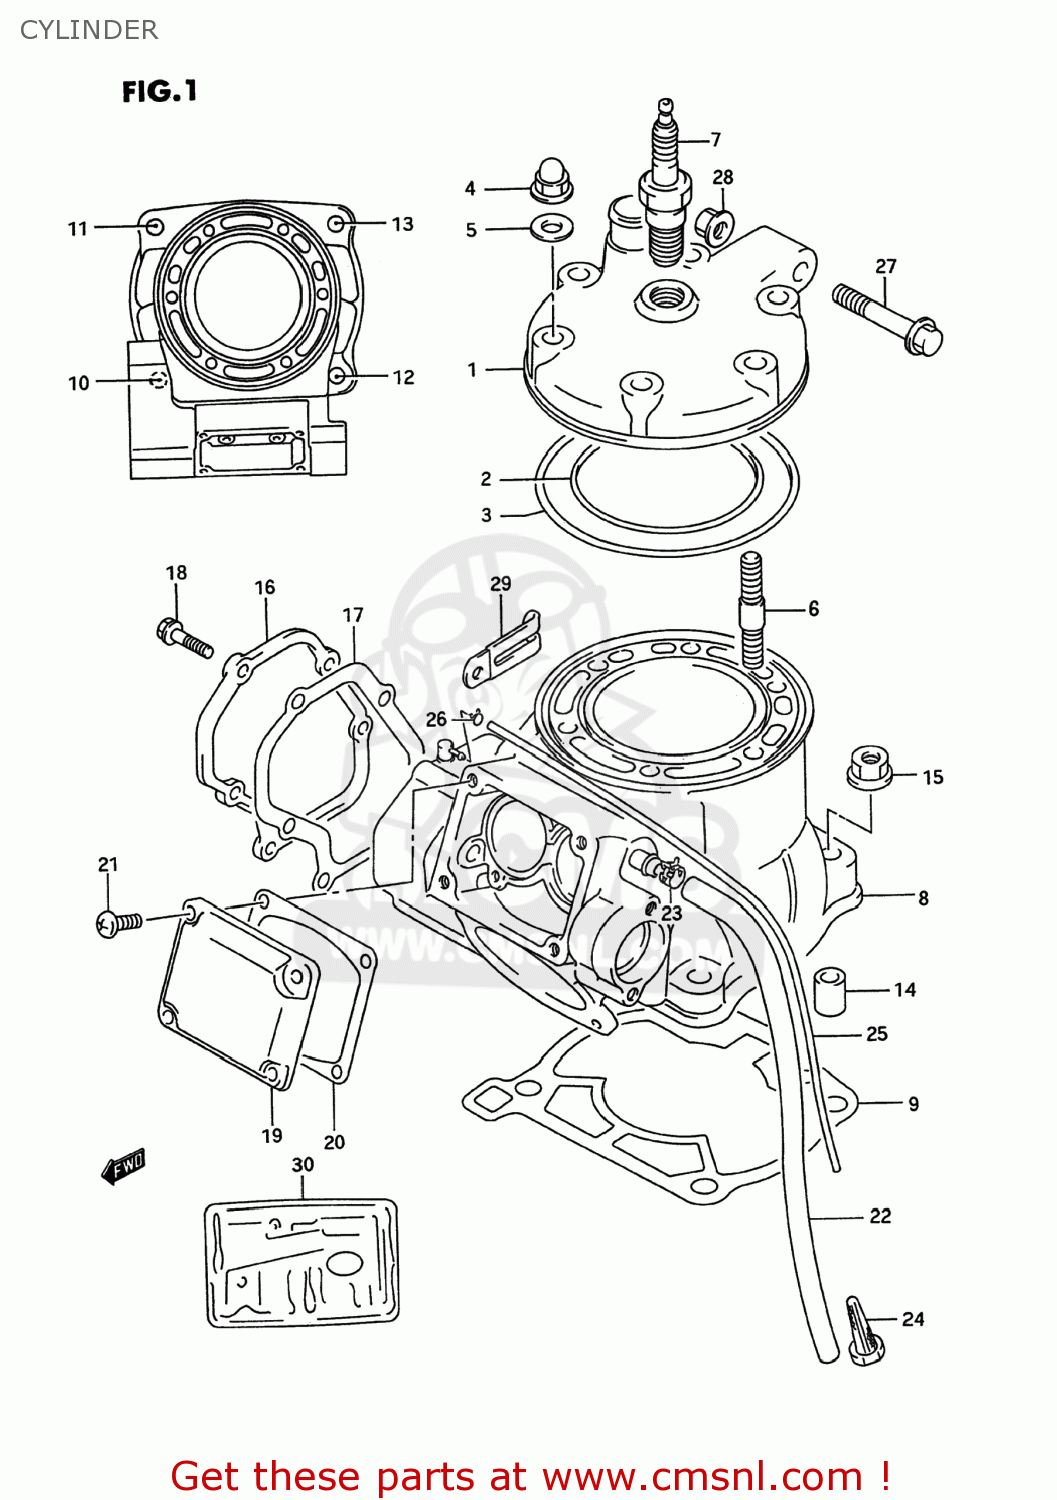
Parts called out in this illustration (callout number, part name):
1	HEAD,CYLINDER
2	O RING,CYLINDER HEAD NO.1
3	O RING,CYLINDER HEAD NO.2
4	NUT
5	GASKET(8.5X17X2.3) (NAS)
6	BOLT,STUD
7	PLUG,SPARK(R4118S-8)
8	CYLINDER SET
9	GASKET,CYLINDER (NAS)
10	STUD 10X30
11	STUD BOLT
12	STUD BOLT (L:40)
13	STUD BOLT (L:45)
14	PIN
15	NUT
16	COVER,CYLINDER NO.1
17	GASKET,CYL COVER (NAS)
18	BOLT
19	COVER,CYLINDER NO.2
20	GASKET,CYLINDER COVER (NAS)
21	BOLT
22	HOSE
23	CLIP
24	FILTER,EXH VALVE BREATHER HOSE
25	HOSE(5X8.2X600)
26	CLIP
27	BOLT(8X45)
28	NUT
29	CLAMP
30	GASKET SET (NAS)
